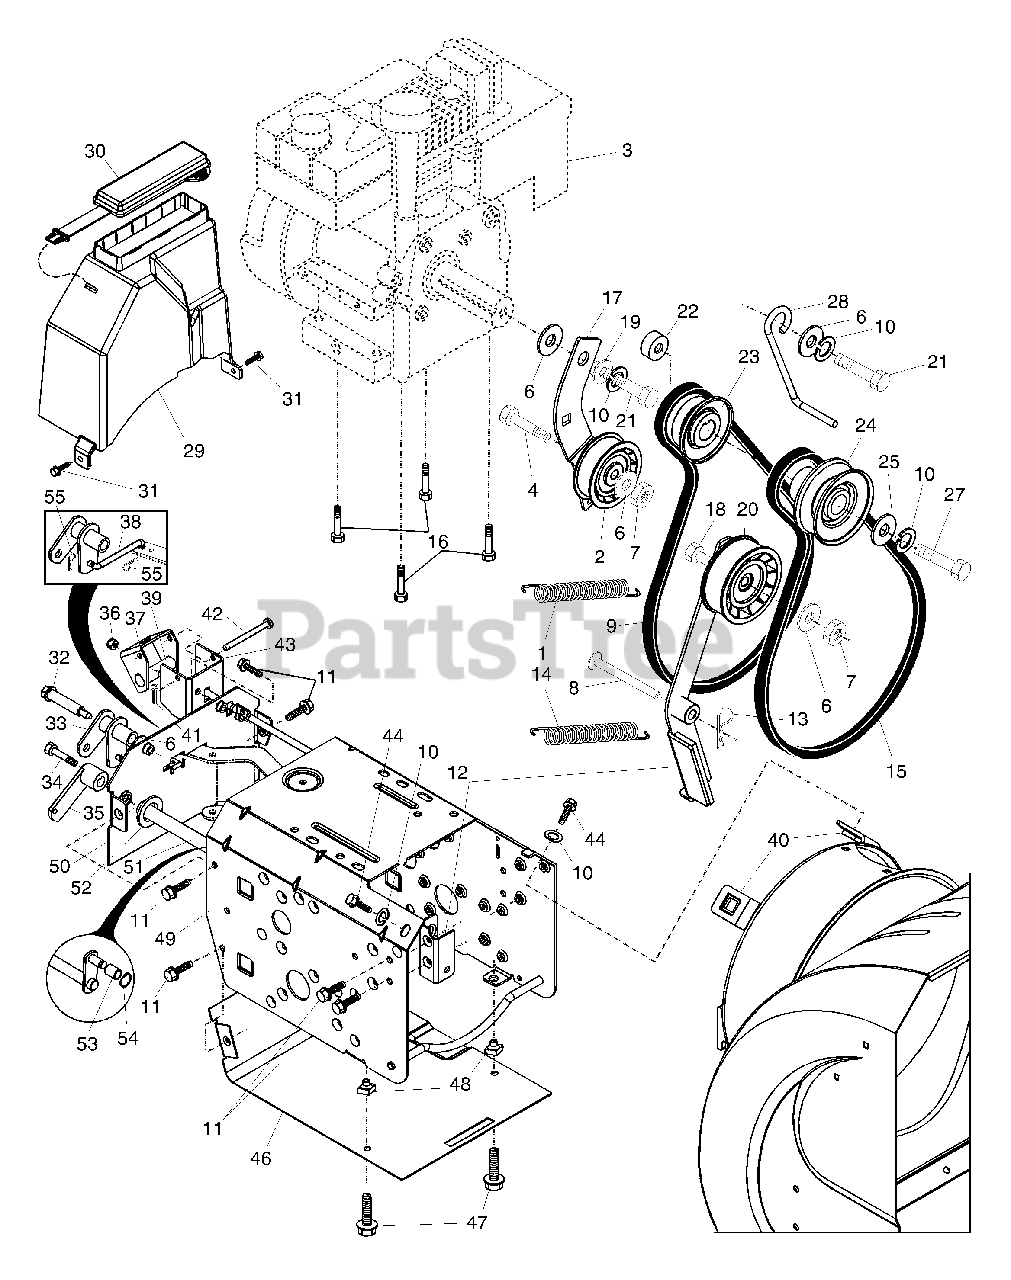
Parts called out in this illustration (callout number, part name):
1	Spring, Traction Idler
2	Pulley, Idler (2-1/4)
4	Screw, Hex Head 5/16-18 x 1-1/4
6	Washer, Flat
7	Nut, Jam, Lock 5/16-18
8	Pin, Idler Pivot
9	V-Belt, Traction Drive
10	Washer, Lock 5/16
11	Screw, Hex Head 5/16-18 x 3/4
12	Impeller Idler Arm & Bracket Assembly
13	Retainer, Hairpin
14	Spring, Brake
15	V-Belt, Impeller Drive
16	Screw, Hex Head 3/8-16 x 1-1/4
17	Arm, Idler
18	Screw, Hex Head 5/16-18 x 1-1/2
19	Bushing, Idler Pivot
20	Pulley, Idler (2-3/4)
21	Screw, Hex Head 5/16-18 x 1
22	Spacer, Engine Pulley
23	Pulley, Engine, Traction Drive
24	Pulley, Engine, Impeller Drive
25	Washer, Flat 3/8
26	Washer, Lock 3/8
27	Screw, Hex Head 3/8-24 x 1-3/8
28	Guide, Belt
29	Cover, Belt
30	Cover, Toolbox
31	Screw, Hex Head 1/4-20 x 1/2
32	Bolt, Shoulder 5/16-18
33	Bellcrank Shifter
34	Screw, Hex Head 1/4-28 x 3/4
35	Arm, Auger Control
36	Nut, Lock 5/16-18
37	Bellcrank Assembly
38	Link, Speed Control
39	Trunnion, Pivot Bracket
40	Nut, Cage 3/8-16
41	Pin, Cotter 1/16 x 1/2
42	Pin, Pivot Bracket
43	Bracket, Bellcrank
44	Screw, Hex Head 3/8-16 x 1-1/2
46	Pan, Frame Bottom
47	Screw, Hex Head 5/16-18 x 3/4
48	Nut, Speed 5/16-18
49	Frame Assembly
50	Plate, Frame End
51	Shaft, Auger Control
52	Washer, Hardened
53	Roller
54	Ring, Retaining
55	Clip, Retainer
